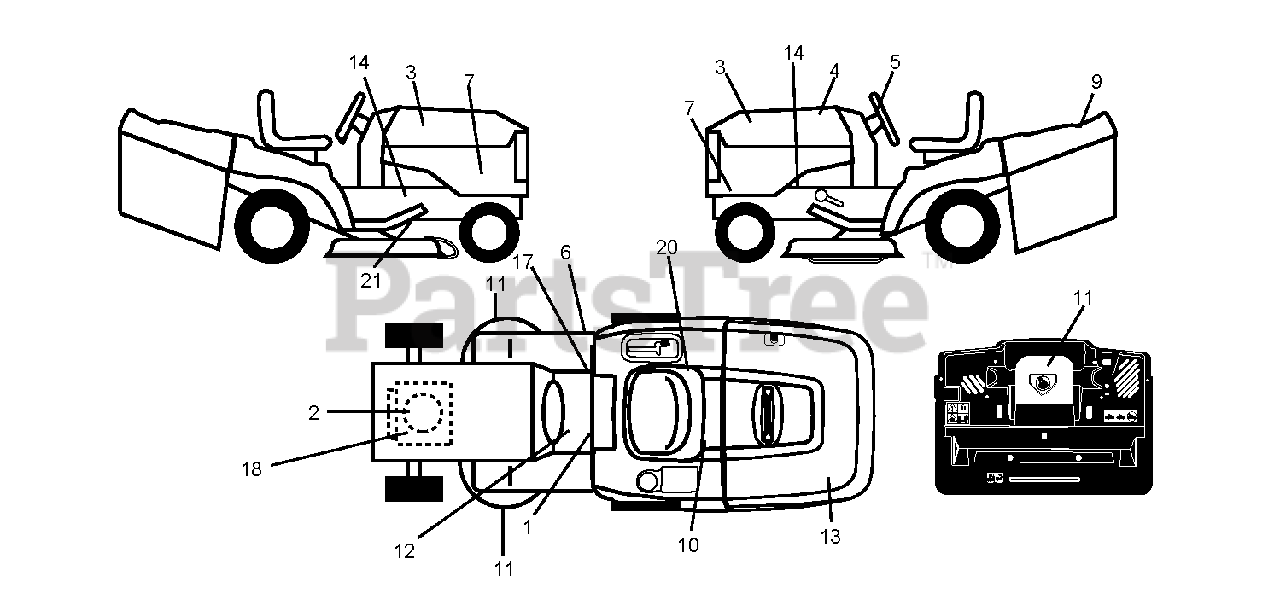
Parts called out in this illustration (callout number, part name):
10	DECAL BTRY SYMBOLS
11	DECAL.INTERNATIONL.CUTFINGER
17	DECAL PARK BRAKE
20	DECAL.BYPASS.FENDER.CRD.LT.YT
